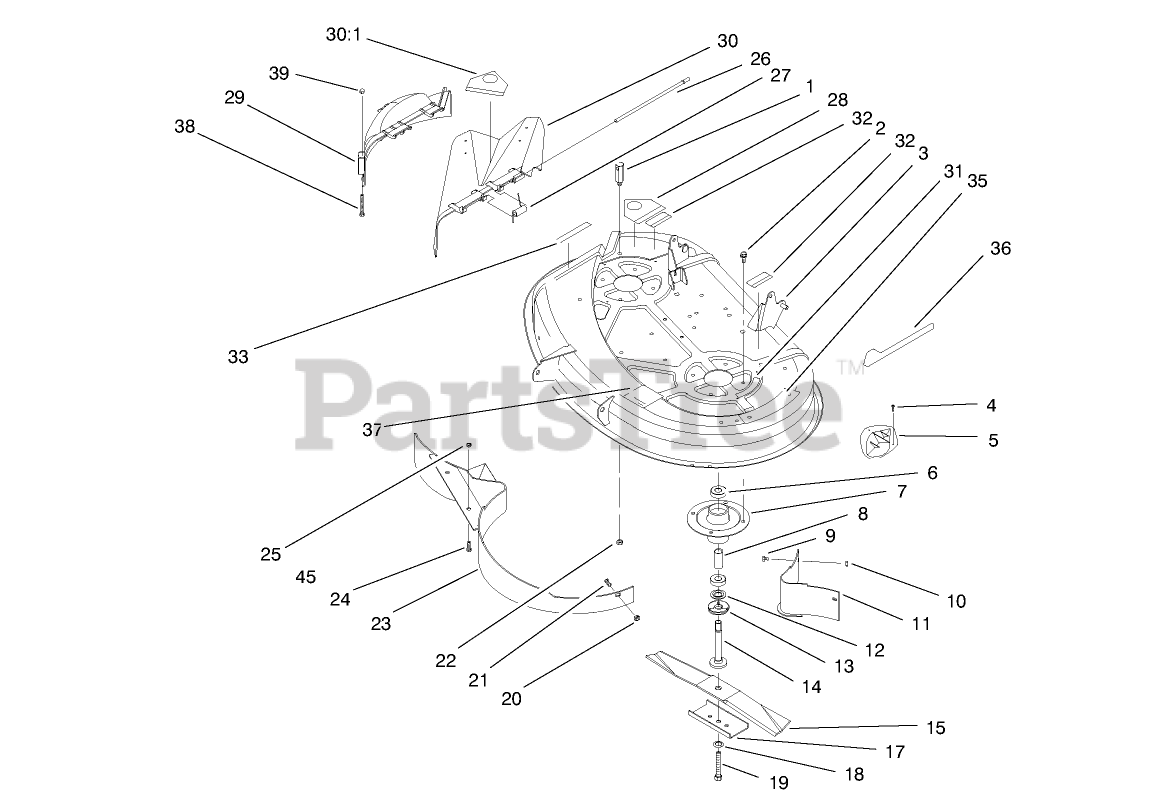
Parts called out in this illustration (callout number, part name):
1	REAR PIVOT POST (PLTD)
2	SCREW-TAPTITE
3	Deck Wa-38"
4	SCREW-PPH
5	PLATE-KICKER
6	BEARING-BALL
7	HOUSING-SPINDLE
8	SPACER
9	SCREW-HH
10	NUT-LOCK, NI
11	BAFFLE ASM
12	SPACER
13	SHIELD-BEARING
14	SHAFT-SPINDLE
17	STIFFENER-BLADE
18	WASHER-BELLEVILLE
19	SCREW-HH
20	NUT-LOCK, NI
21	BOLT-CARR
22	NUT-LOCK, NI
23	BAFFLE ASM
24	SCREW-HH
25	NUT-LOCK, NI
26	ROD-HINGE DEFLECTOR
27	SPRING
28	DECAL-DANGER
29	COVER-RECYCLER
30	DEFLECTOR ASM
30:1	DECAL-DANGER
31	DECAL-DANGER, SHIELD
32	DECAL-WARNING
33	DECAL-DANGER, DEFLECTOR
35	DECAL-DANGER
36	DECAL-RECYCLER DECK 38"
38	SCREW-HH
39	NUT-CAP
